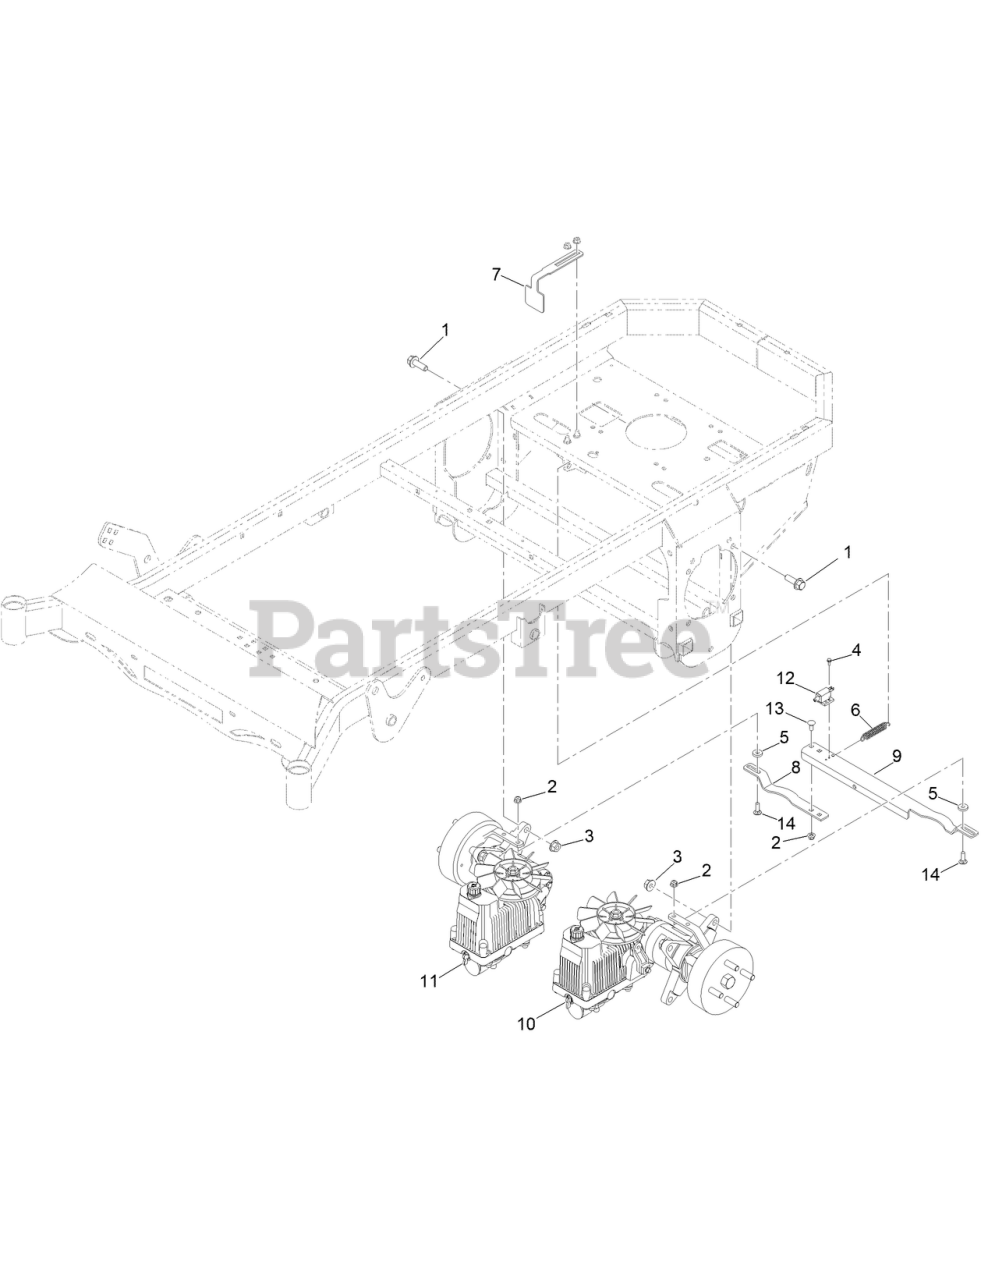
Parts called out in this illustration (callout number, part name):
1	SCREW-HHF
2	NUT-HF, NI
3	NUT-HHF
4	8-32 X 1/2 IND. HWH SLOT TYPE F TCS ZINC
5	.312 ID X .875OD X .1875 THK F/W NYL
6	MWR BRAKE PEDAL RELEASE SPRING
7	STAND TRANS BRAKE INTERLOCK BRKT PAINT
8	MWR PARK BRAKE BRKT RT PAINT
9	MWR PARK BRAKE BRKT LT PAINT
10	HTE10 LT SIDE HYDROST TRANSM FOR RZ HUB
11	HTE10 RT SIDE HYDROST TRANSM FOR RZ HUB
12	NO PLUNGER LIMIT SWITCH
13	BOLT-CARR
14	BOLT-CARR
